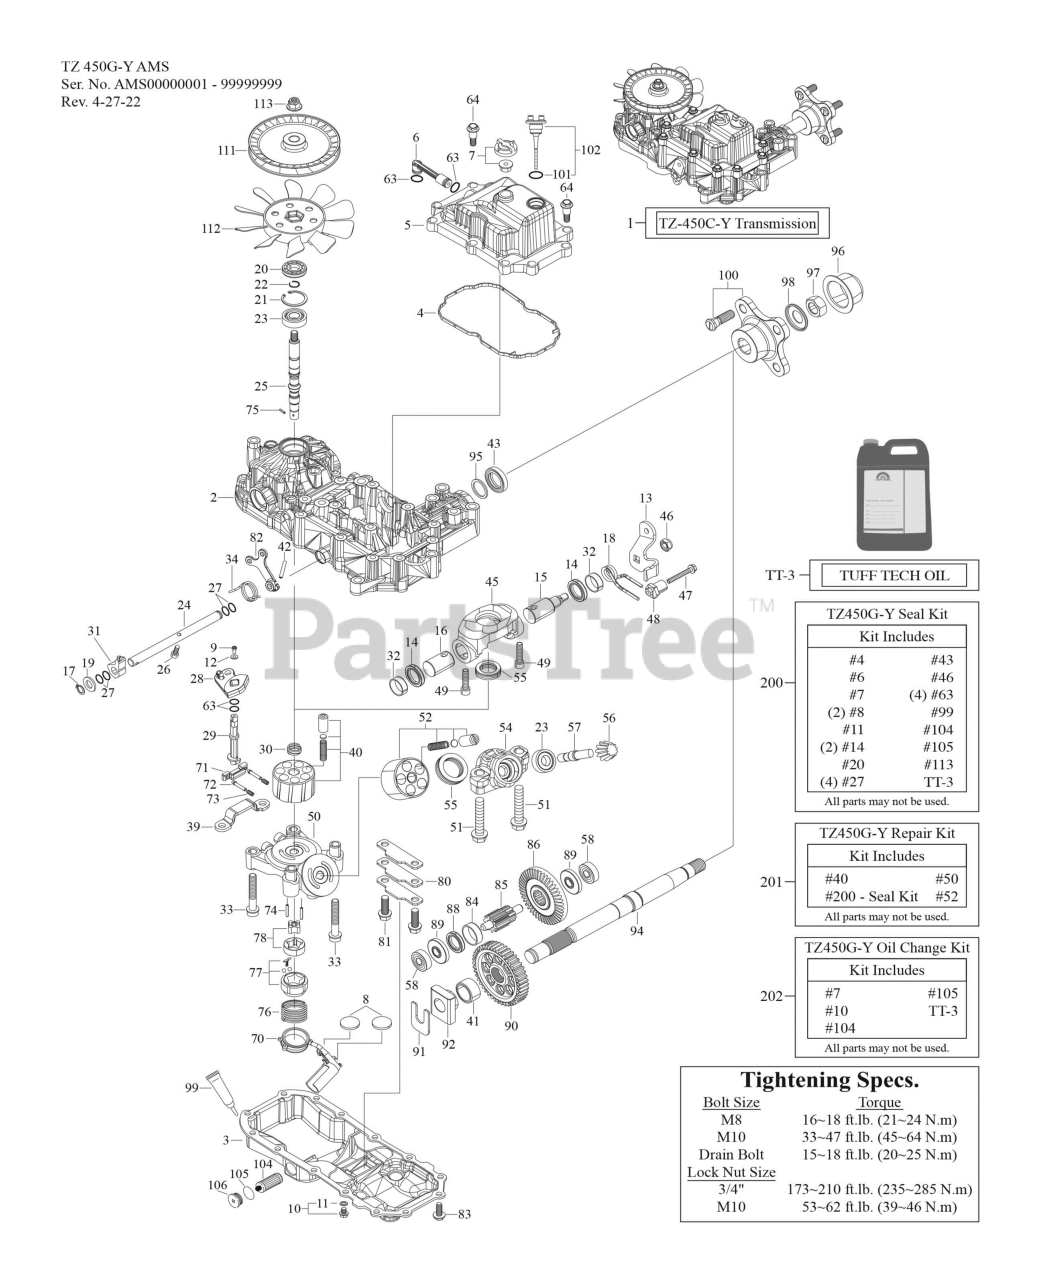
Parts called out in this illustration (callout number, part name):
1	HYDRO TRANSMISSION (RH)
2	UPPER HOUSING Y
3	LOWER HOUSING FX
6	BYPASS PIPING
10	DRAIN BOLT KIT
11	WASHER-SEAL DRAIN BOLT
12	WASHER 4.5X10X1
13	CONTROL LEVER Y
15	CONTROL SHAFT
16	CONTROL SHAFT SHORT
18	TORSION SPRING
19	FLAT WASHER 12
20	SEAL-OIL 15X35X07
23	BALL BEARING
26	SOCKET BOLT 6X16
30	SPRING-CYL BLOCK
31	BRAKE FORK 20 CR
32	CONTROL BUSH LFB2510
33	HEX BOLT M10X65
34	SPRING, BRAKE YA
39	CHECK STOPPER PFG
40	CYLINDER BLOCK KIT
42	SPRING PIN 5 x 3
43	SEAL TC284008
50	CENTER CASE
52	BLOCK KIT-PISTON & MOTOR
54	MOTOR HOUSING A
55	THRUST BEARING
58	BEARING 6201 CN
64	TAP SCREWPING 8X
70	BRACKET ASSY FT3
73	BYPASS SPRING
75	PIN 2.5 x 9.8
76	SPRING-CHARGE PUMP
77	PUMP CASE ASSEMBLY
83	TAP SCREWPING
84	FINAL PINION COLLAR
85	FINAL PINION SHAFT
86	REDUCTION GEAR
88	REDUCTION COLLAR
89	WASHER 14.1X30X3.5
97	LOCK NUT 3/4-16
98	FLANGE SPACER
105	RING-"O" LWR CASE CAP
113	NUT-LOCK PMP SHAFT
200	SEAL KIT W/OIL
201	REPAIR KIT W/OIL
202	OIL CHANGE KIT (TZ-450)
TT-3	TUFF TECH OIL 3 LITER BOTTLE
